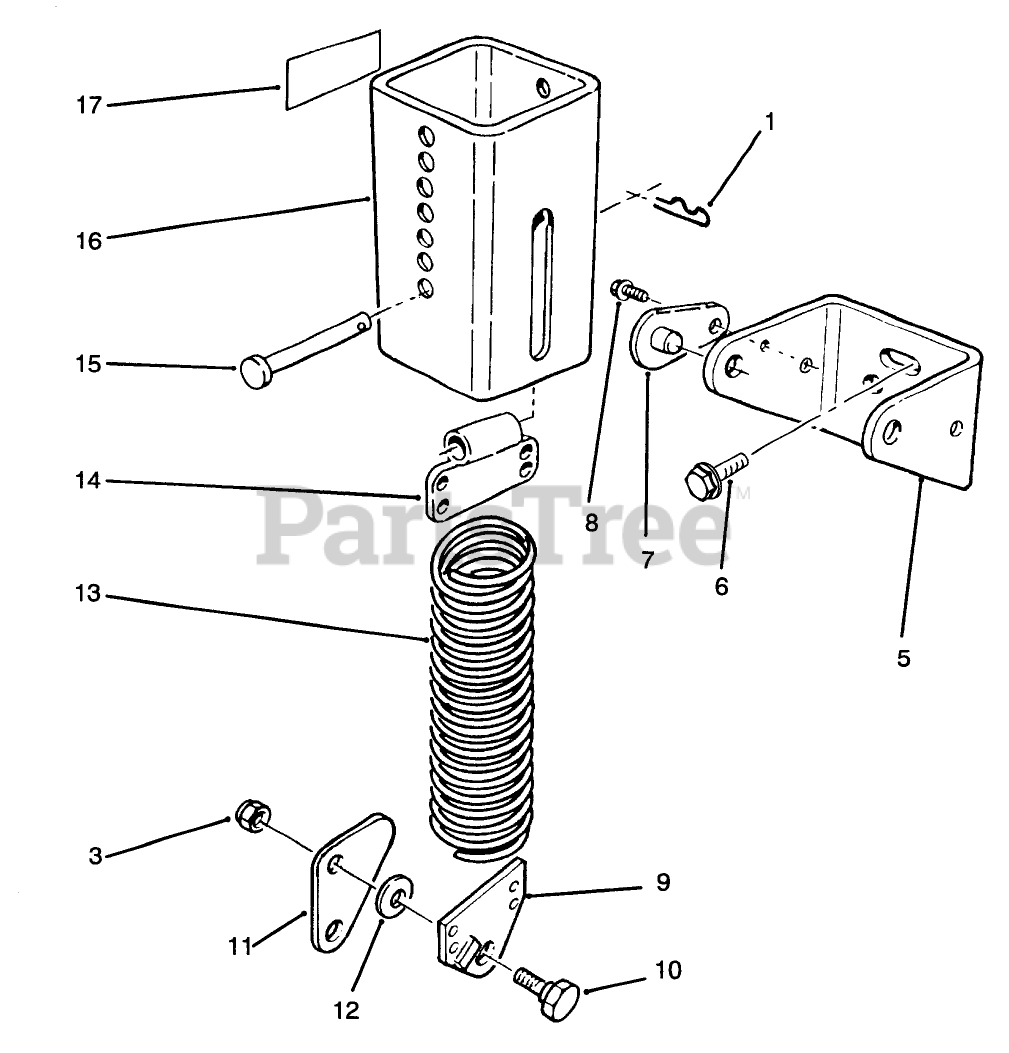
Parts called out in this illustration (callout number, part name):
1	PIN-HAIR
3	NUT-LOCK, NI
5	Bracket-Support
6	SCREW-HHF
7	PIN-LOCK
8	SCREW
9	End Spring
10	BOLT-SHOULDER
11	Link
12	WASHER-FLAT
13	Spring-Extension
14	End Spring
15	PIN-CLEVIS
16	Asm-Spring Cover
17	DECAL-WARNING
